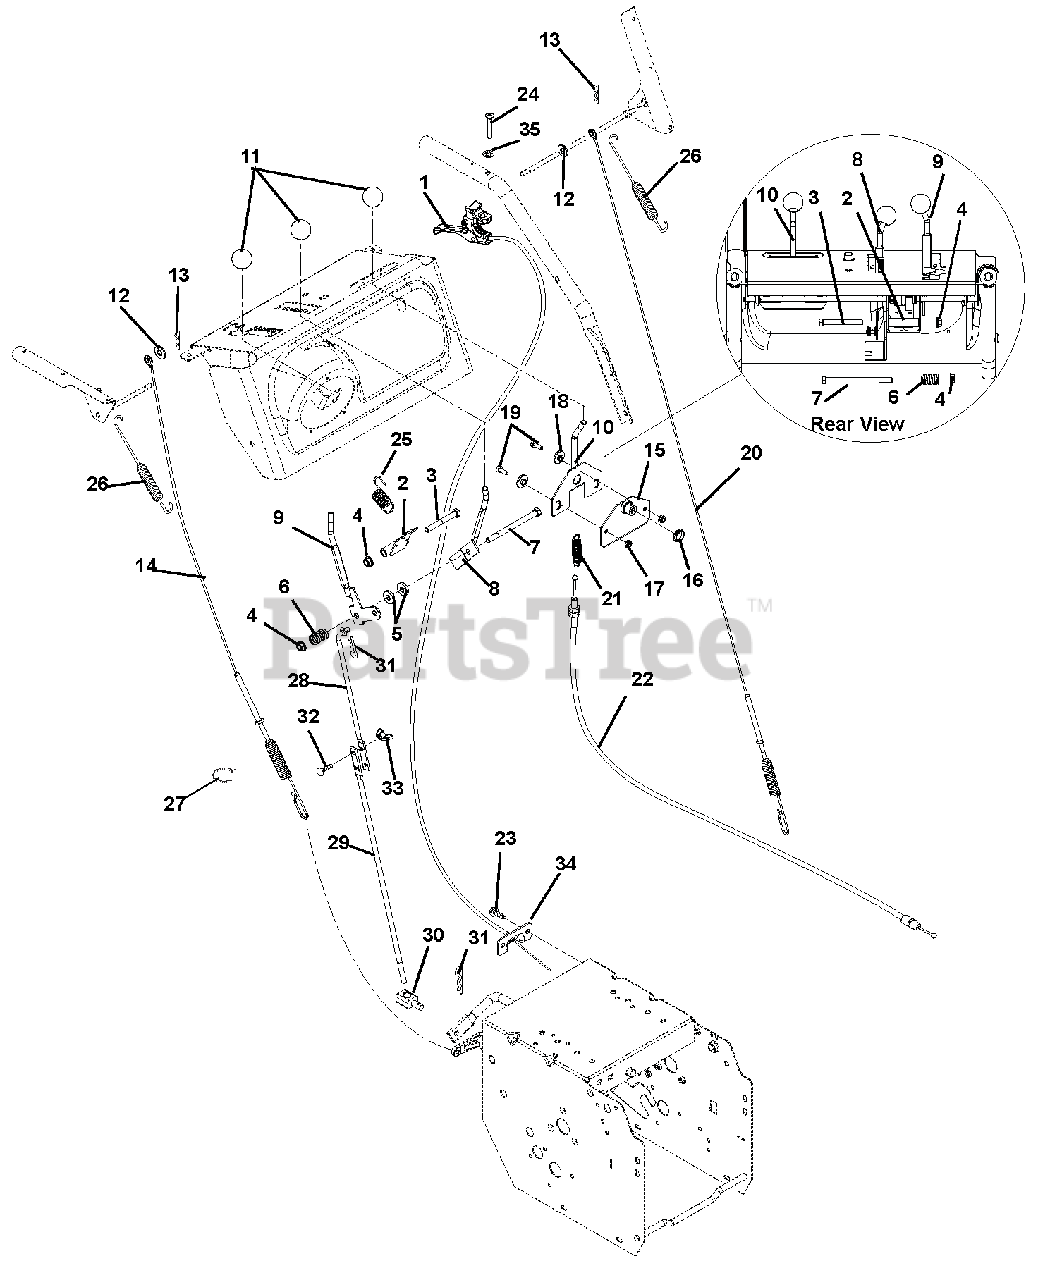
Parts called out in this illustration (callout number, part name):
1	CABLE-TRIGGER-REMOTE WHEEL-DEL
2	ARM, INTERLOCK
3	@BLT-HEX .38-16X3.00 GR5 YWZC
4	@NUT-LK-TOP-FLG .38-16 YWZC
5	WSHR-FL-STL .406X1.00X.188 YWZ
6	SG-COMP .125X.781X1.250
7	@BLT-HEX .38-16X5.00 GR5 YWZC
8	CONTROL, DEFLECTOR
9	LEVER, SHIFT
10	LEVER, CHUTE CONTROL
11	KNOB,BALL -BLACK 1.47" .375-16
12	@WSHR-FL-STL.281X.62X.065 YWZC
13	PIN-HAIR INT .06X.18X.77
14	CABLE, ATTACHMENT
15	MOUNT, CHUTE CONTROL
16	BUSHING, POLYLINER-.75 SNAPIN
17	@NUT-LK-TOP-FLG .25-20 YWZC
18	BSHG-FLG .265X.448X.243X1.00
19	@BLT-HEX .25-20X.75 GR5 YWZC
20	CABLE, TRACTION - DELUXE
21	SG-TENS .048X.44X1.75 WLD 9
22	CABLE, CHUTE LOCK
23	@SCR-TAP .25-20X.50 HWH TR YWZ
24	SCR-MCH .25-20X1.50 OVAL HD
26	SG-TENS .056X.60X4.40
27	CABLE TIE LG 5-1/2
28	ROD, SHIFT-UPPER
29	ROD, SHIFT-LOWER
30	PIVOT,SHIFT ROD .375-16(TRUNN)
31	PIN-HAIR, ENDRIES #25 YWZC
32	@BLT-RDHDSQNK .25-20X.75 G5YZ
33	NUT-LK WING .250-20 YWZC
34	BRACKET, CABLE MOUNT
35	WSHR-LK-INT .250 TH TYA
